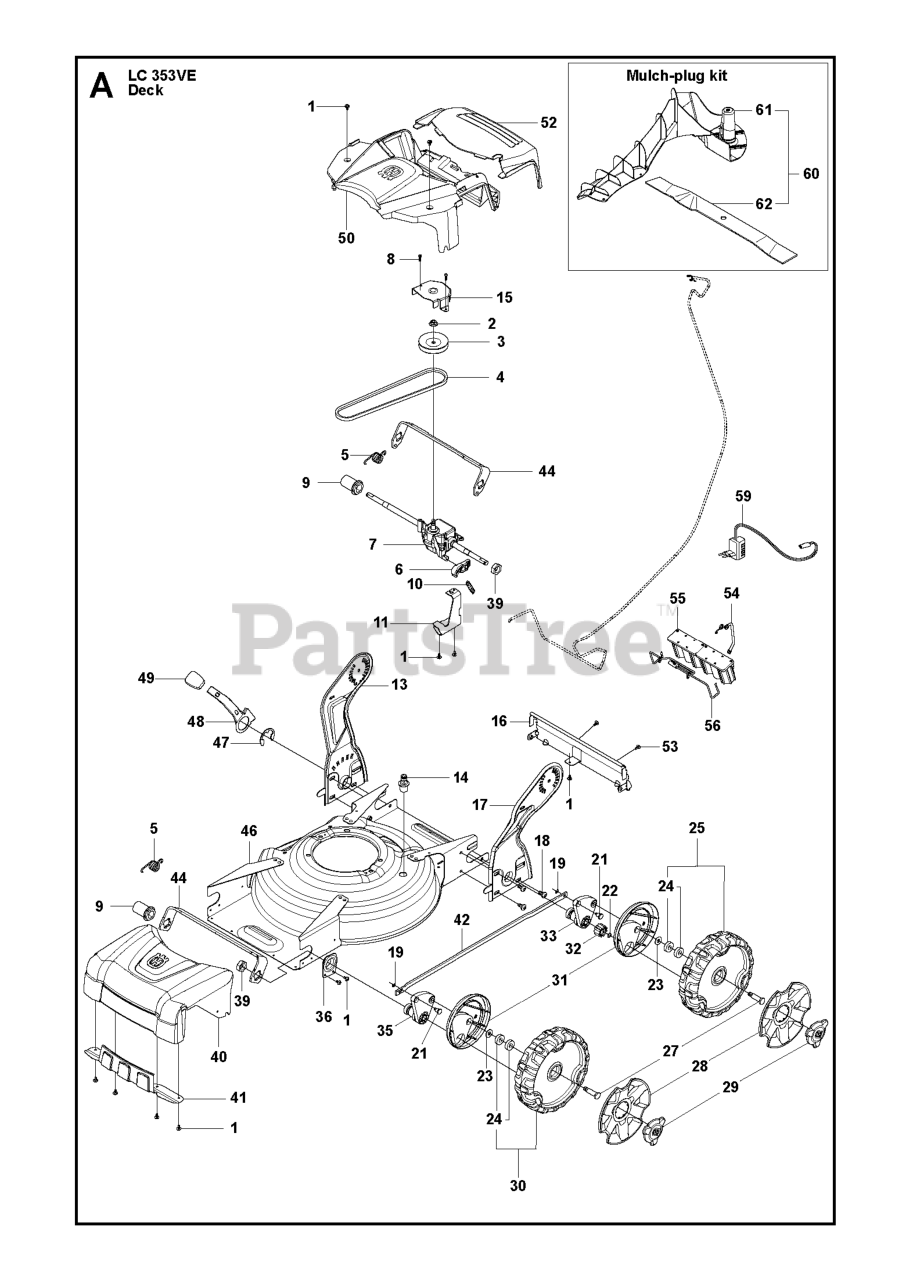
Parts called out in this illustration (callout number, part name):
1	SCREW ITXPANTT M5X10 ZPB (A00
4	BELT WRAPPED V-BELT Z 31 3/4"
8	SCREW ITXPANT T50X16 ZN/FE (A
19	FASTENER
24	BALL BEARING
30	WHEEL ASSY 210, IDLE, MEDIUM
53	SCREW ITXPANTT M5X10 ZPB (A00
